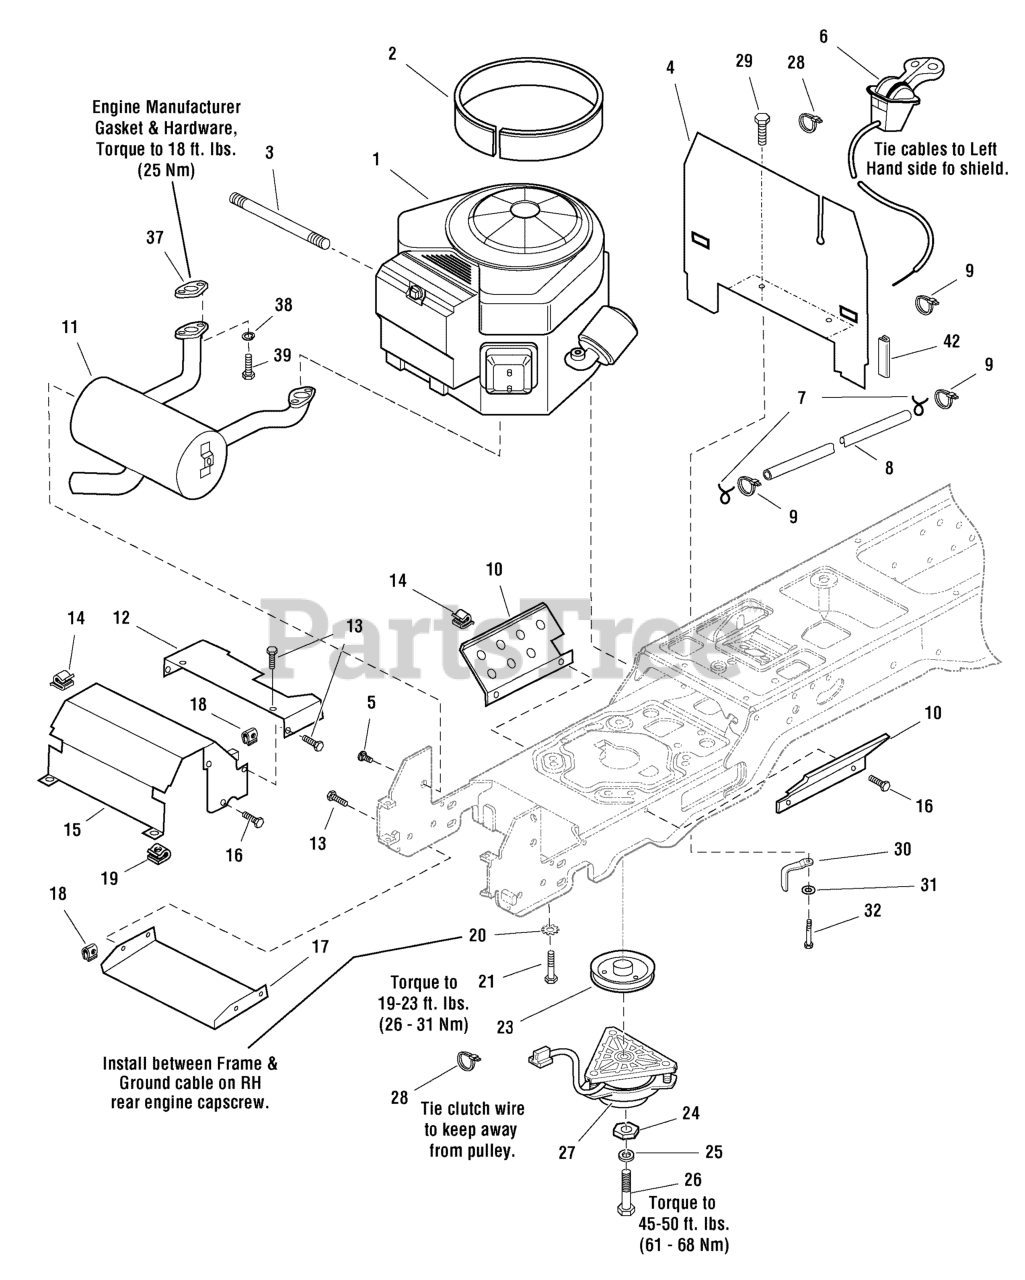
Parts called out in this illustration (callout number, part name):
1	ENGINE, 22 HP Briggs & Stratton
2	EDGING, Airduct
3	HOSE, Oil Drain
4	HEAT SHIELD
5	CAPSCREW, Hex Head, Taptite, 5/16-18 x 1/2
6	THROTTLE CONTROL
7	CLAMP, Hose
8	HOSE, Fuel
9	TIE, Self Locking, 7-5/16 Long
10	SHIELD, Side, Heat
11	MUFFLER ASSEMBLY
12	DUCT, Muffler Extension
13	CAPSCREW, Hex, Whiz Lock, 1/4-20 x 5/8
14	CLIP, Wire
15	DUCT, Muffler Top
16	CAPSCREW, Hex Head Taptite, 1/4-20 x 3/8
17	SHIELD, Muffler Bottom
18	NUT, Speed, 1/4-20
19	NUT, Speed, Lug Type, 5/16-18
20	WASHER, Locking, External Teeth, 3/8
21	CAPSCREW, Hex Head, Taptite, 3/8-16 x 1-1/2
23	PULLEY, Engine
24	WASHER, Hex, 7/16 x 1-1/2
25	WASHER, Locking, 7/16
26	CAPSCREW, Hex Head 7/16-20 x 3-1/2
28	TIE, Self Locking, 3-5/8 Long
29	CAPSCREW, Hex Head Taptite, 1/4-20 x 1/2
30	RETAINER, Clutch
31	WASHER, Flat, 3/8
32	CAPSCREW, Hex Head 3/8-16 x 1
34	CAPSCREW, Allen Head 1/4-20
35	NUT, 1/4-20 Hex Serrated Flange
37	GASKET, Exhaust
38	LOCKWASHER, 5/16
39	CAPSCREW, Socket Head, 5/16-18 x 7/8, G8
